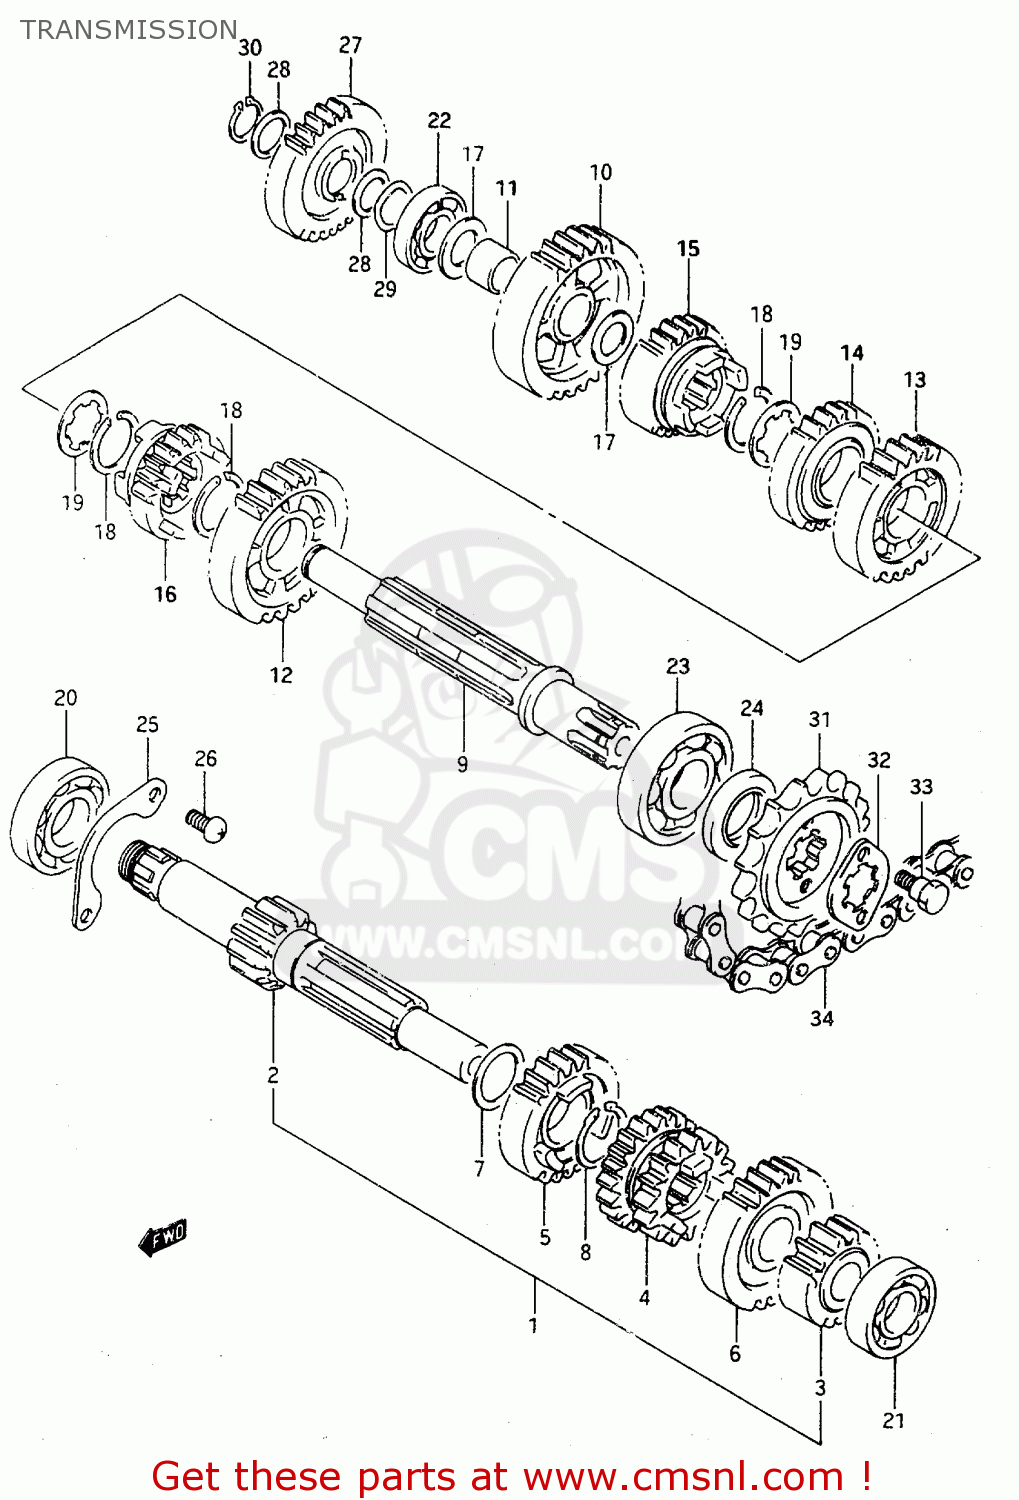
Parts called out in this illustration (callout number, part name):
1	COUNTER SHAFT
2	SHAFT,COUNTER(NT11)
3	GEAR,2ND DRIVE(NT:14)
4	GEAR, 3RD/4TH DRIVE (NT:15/21)
5	GEAR,5TH DRIVE(NT:24)
6	GEAR, 6TH DRIVE (NT:25)
7	WASHER
8	CIRCLIP
9	SHAFT,DRIVE
10	GEAR, 1ST DRIVEN (NT:29)
11	BUSH(15X18X13)
12	GEAR, 2ND DRIVEN (NT:26)
13	GEAR,3RD DRIVEN(NT:21)
14	GEAR,4TH DRIVEN(NT:23)
15	GEAR,5TH DRIVE
16	GEAR, 6TH DRIVEN (NT:20)
17	WASHER,THRUST
18	CIRCLIP
19	WASHER,LOCK
20	BEARING(20X47X10.5)
21	BEARING
22	BEARING(15X35X8)
23	BEARING(20X52X12.5)
24	OIL SEAL (20X35X5)
25	RETAINER,CNTR SHAFT BEARING
26	SCREW 6X12
27	GEAR,KICK STARTER IDLE
28	THRUST WASHER
29	WAVE WASHER
30	CIRCLIP
31	SPROCKET,ENGINE(NT:17)
32	PLATE
33	BOLT(6X13)
34	CHAIN ASSY, DRIVE (DID 428VCA*130LE)
